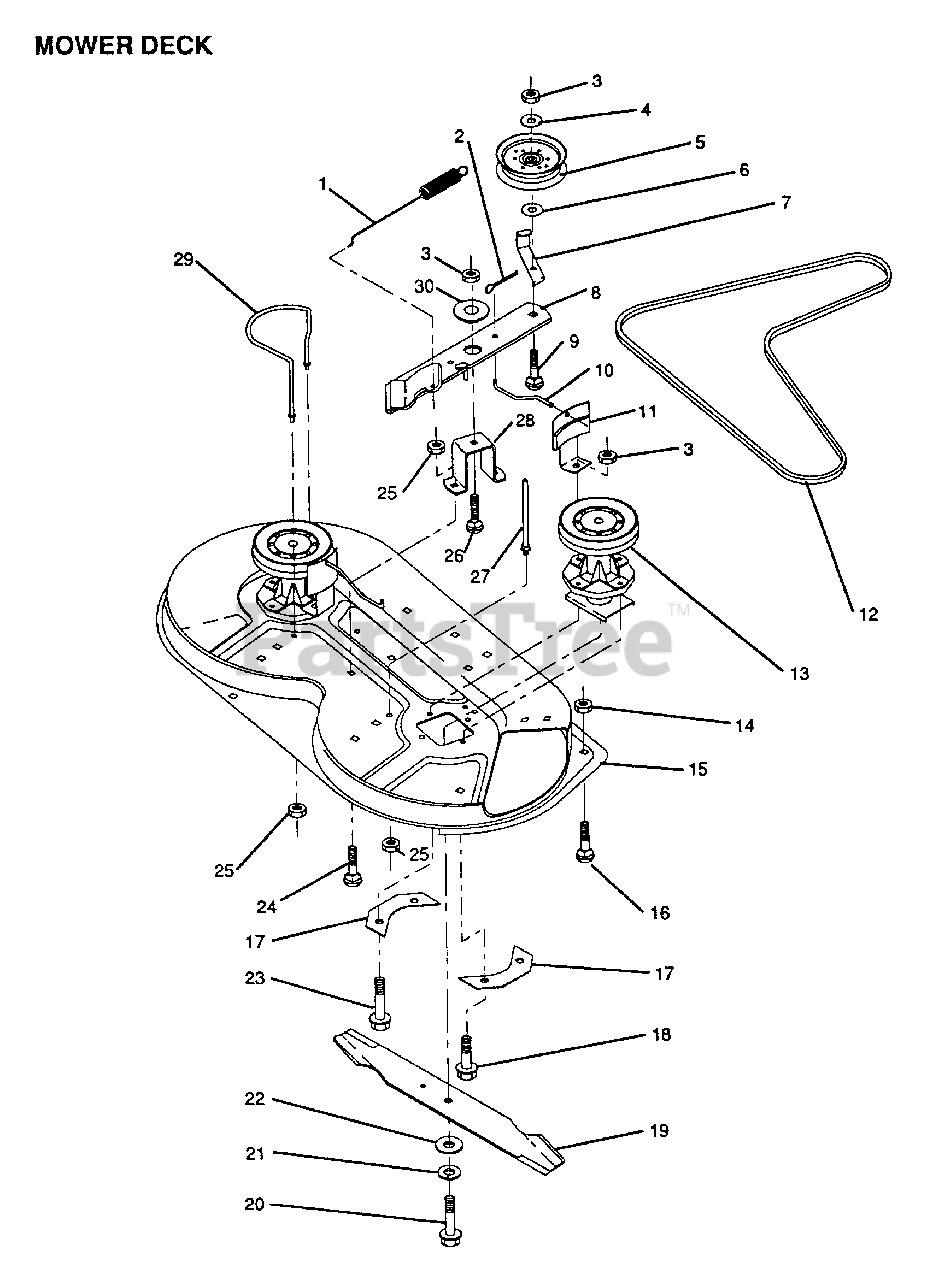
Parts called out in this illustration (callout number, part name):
4	WASHER
5	PULLEY IDLER
6	WASHER GT
8	IDLER ARM ASS'Y
9	BOLT CARRIAGE
10	ROD BRAKE
11	BRAKE LT
12	BELT.MOWER.79.75
13	MANDREL ASS'Y
16	BOLT
17	SUPPORT PLATE LT
18	SCREW
19	"BLADE.36""LOW LIFT"
20	BOLT.3/8-24X1-1/2
22	WASHER
23	SCREW
24	BOLT
26	BOLT D
27	"GUIDE,REAR BEL RH"
28	"SUPT,IDLER ARM"
29	GUIDE BELT LH
30	SPACER RETAINER
